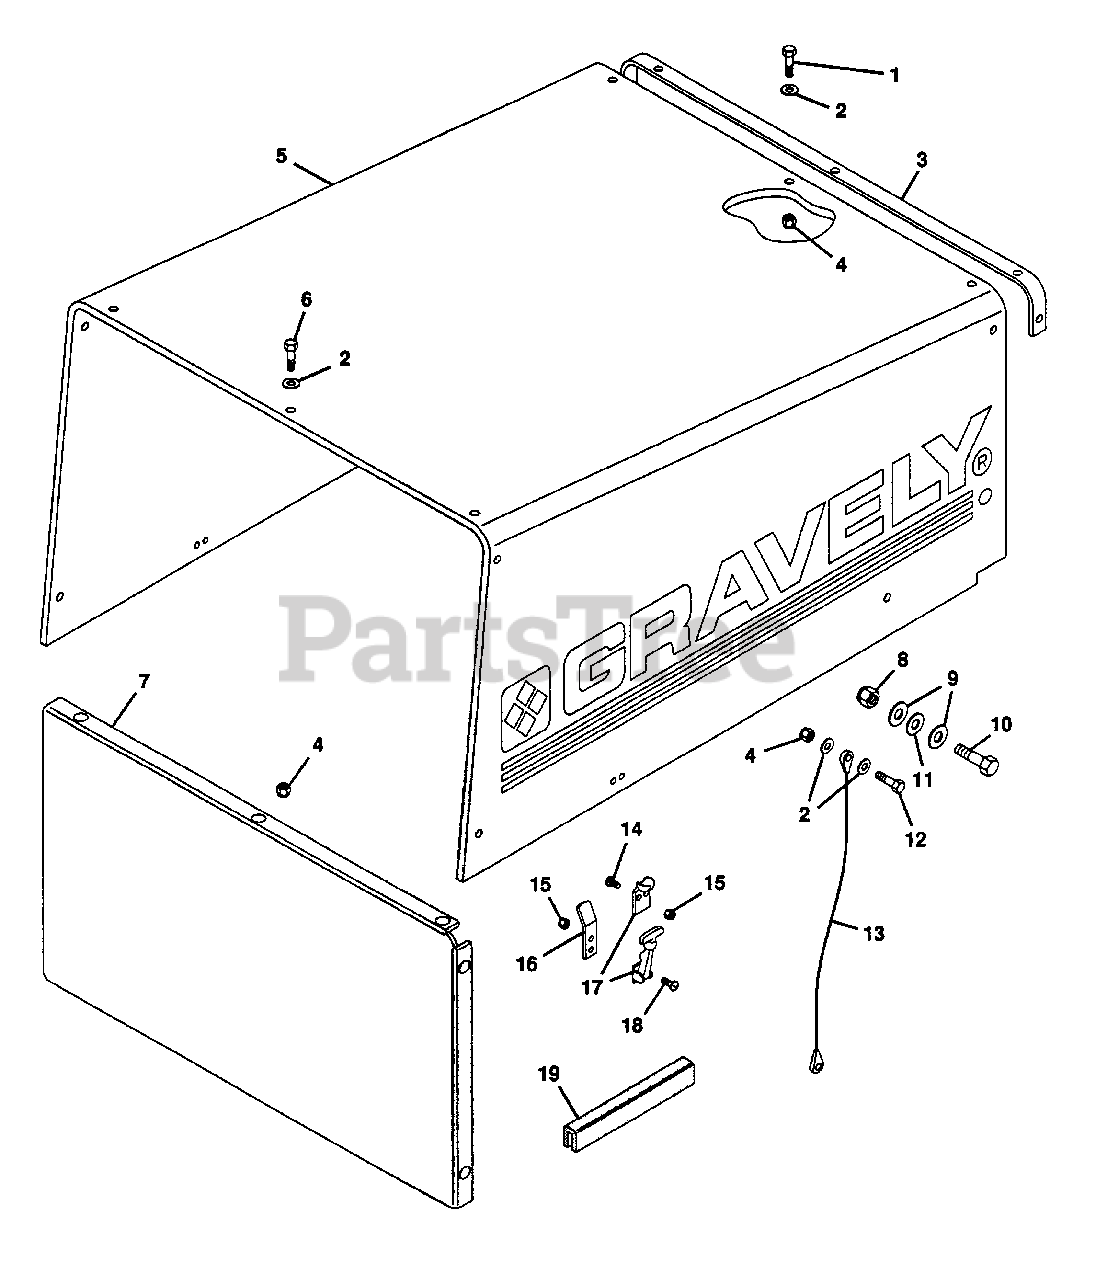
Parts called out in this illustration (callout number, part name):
1	Bolt, Hex 1/4-20x.750
2	Washer, Flat .281x.625x.065
3	Brace Hood
4	Nut, Lock 1/4-20
5	Hood, Silk Screen
6	Bolt, Hex 1/4-20x.625
7	Baffle, Hood
8	Nut, Lock 3/8-16
9	Washer, Flat .406x.812x.065
10	Bolt, Hex 3/8-16x.875
11	Washer, Nylon .375x.75x.060
12	Bolt, Hex 1/4-20x.875
13	Cable, Hood
14	Screw, Machine 10-24x.50 PHD
15	Nut, Lock 10-24
16	Plate, Guide
17	Latch
18	Screw, Machine 10-24x.75 PHD
19	Strip, Cowl
